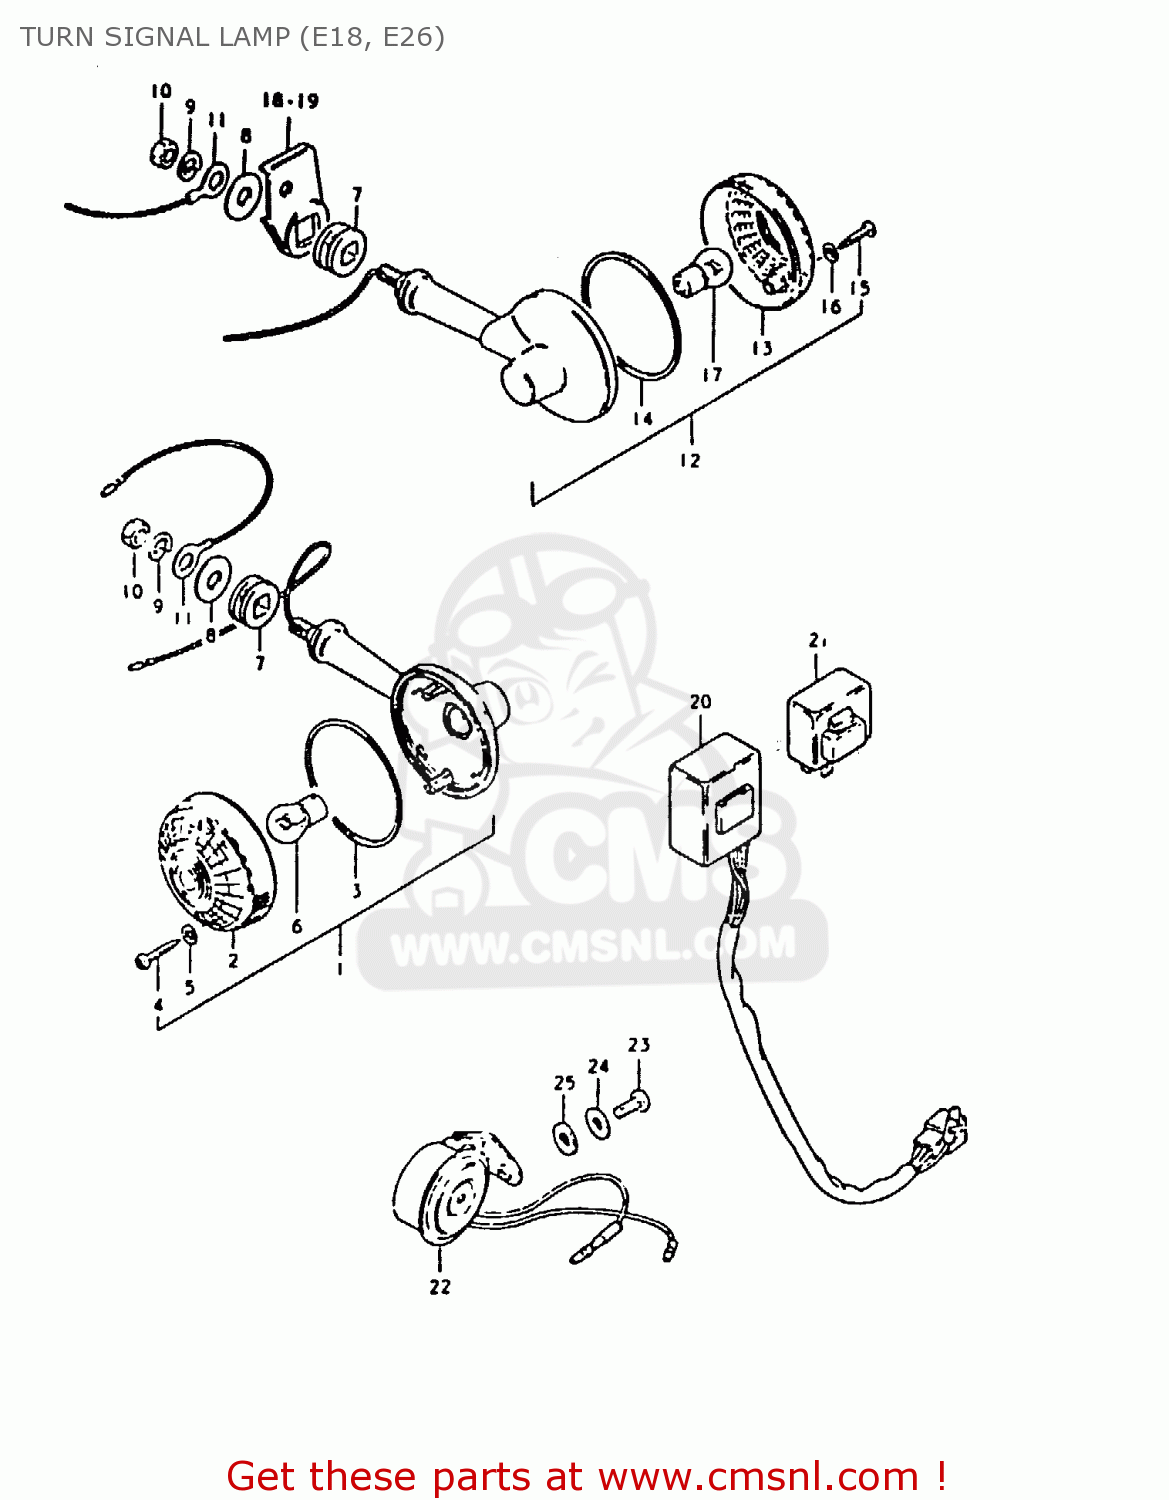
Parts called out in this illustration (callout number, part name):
1	LAMP, REAR TURN SIGNAL
2	LENS
3	GASKET (NAS)
4	SCREW (4X30)
5	GASKET (NAS)
6	BULB(12V21W)
7	CUSHION
8	WASHER (10.5X30X2.3)
9	LOCK WASHER
10	NUT
11	LEAD WIRE,EARTH
12	LAMP, REAR TURN SIGNAL
13	LENS
14	GASKET (NAS)
15	SCREW (4X30)
16	GASKET (NAS)
17	BULB(12V21W)
18	BRACKET,RR TURNSIGNAL LAMP,R
19	BRACKET,RR TURNSIGNAL LAMP,L
20	UNIT,TURN SIGNAL CONTROL
21	RELAY,TURN SIGNAL
22	BUZZER ASSEMBLY,TURN SIGNAL
23	SCREW
24	WASHER
25	WASHER(6X13X2)
